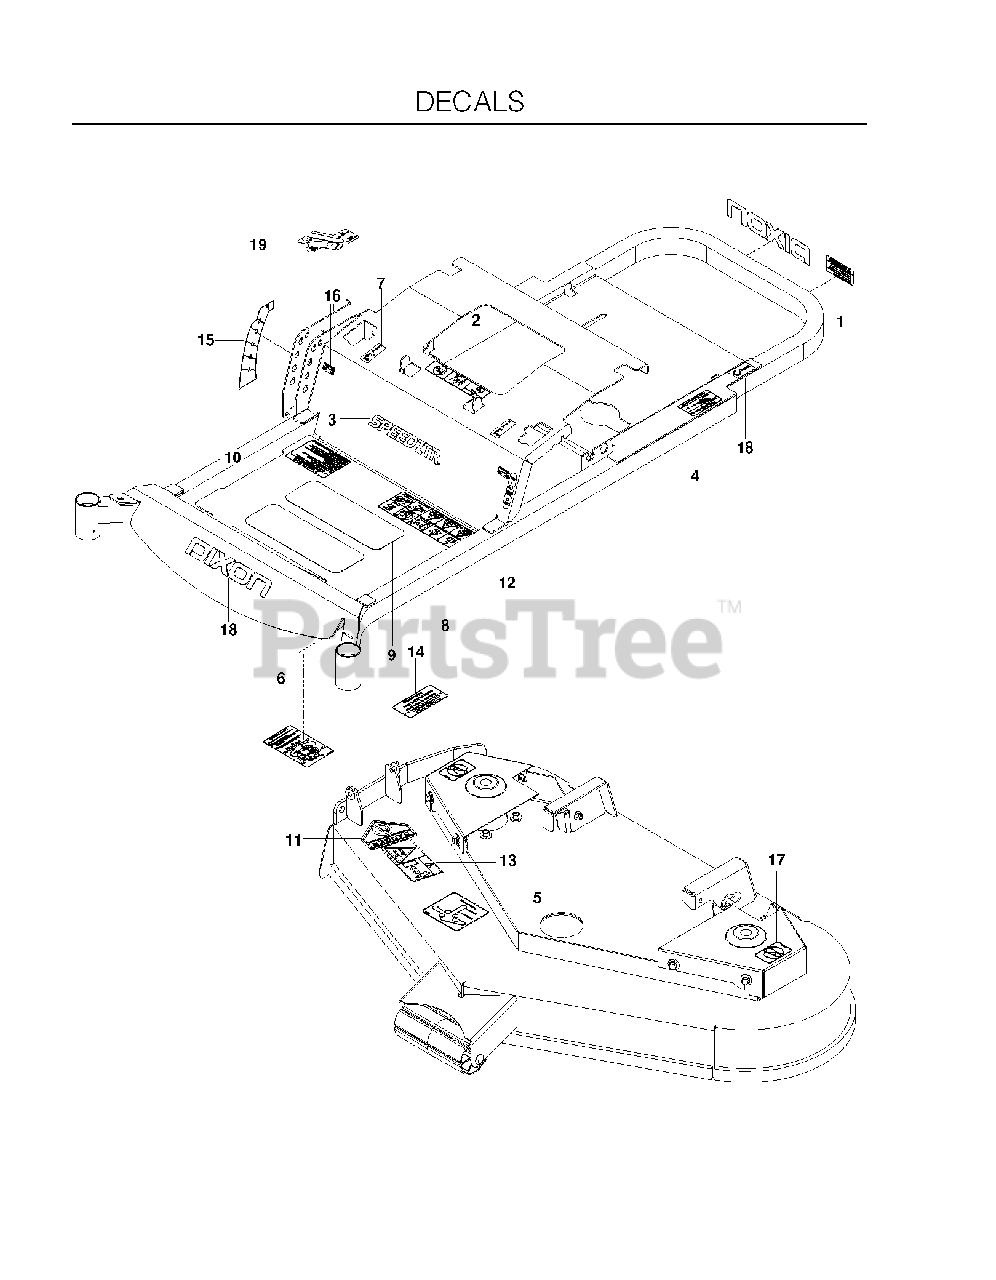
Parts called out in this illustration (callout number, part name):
1	DECAL, PROP. 65
3	DECAL, SPEEDZTR, 8"
4	DECAL, DO NOT MOUNT
5	DECAL, BELT ROUTING
6	DECAL, SERVICE
7	DECAL, MOTION CONTROL
8	DECAL, SAFETY WARNING
9	ANTI-SKID PAD
10	DECAL, WARNING
11	DECAL, CPSC
12	DECAL, PARK BRAKE
13	DECAL, EURO SEVERING
14	DECAL, DANGER
15	DECAL, HEIGHT
16	DECAL, TRACKING
17	DECAL, NO STEP
19	DECAL, CONTROLS PANEL, DIX
